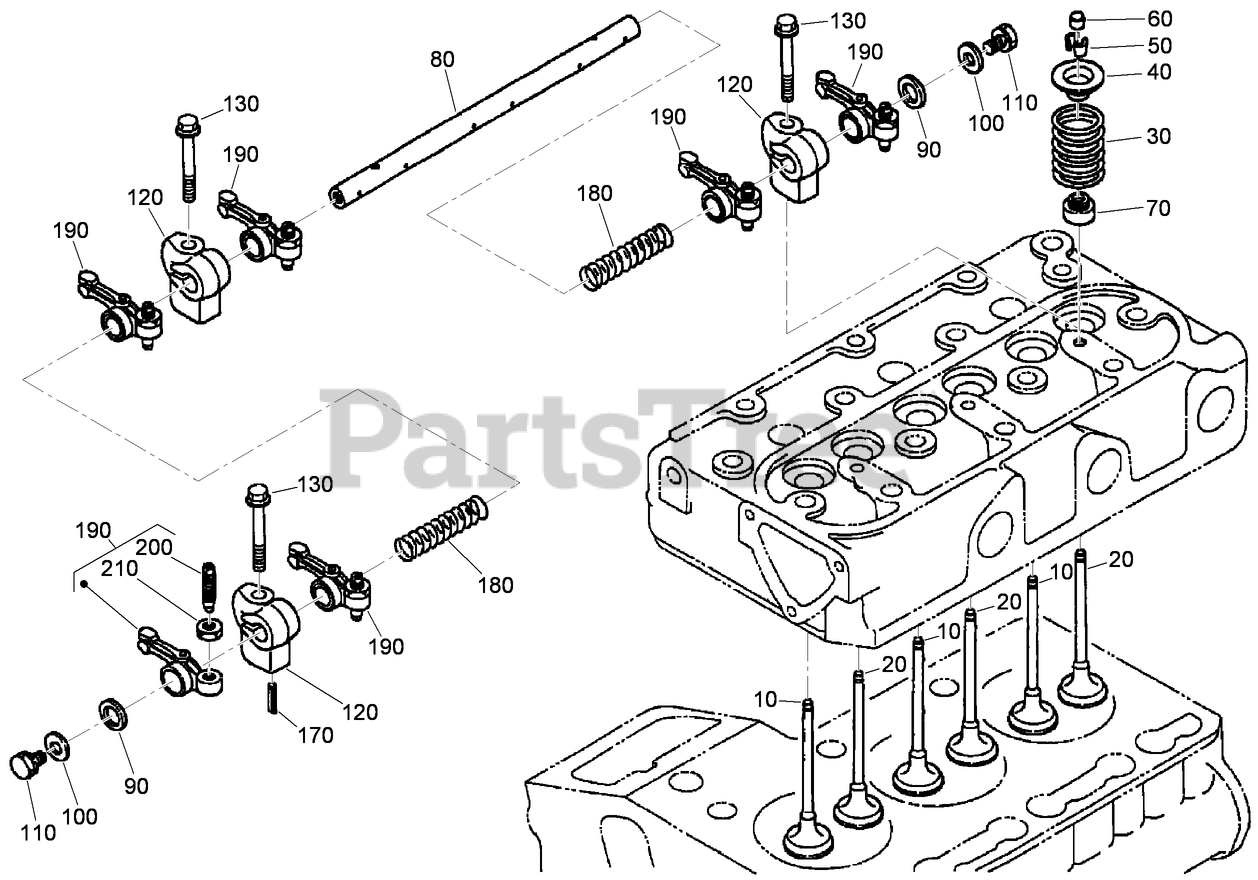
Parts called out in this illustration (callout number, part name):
10	VALVE-INLET
20	VALVE-EXHAUST
30	SPRING-VALVE
40	RETAINER-SPRING, VALVE
50	COLLET-SPRING, VALVE
60	CAP-VALVE
70	SEAL-STEM, VALVE
80	SHAFT-ARM, ROCKER
90	WASHER
100	WASHER-PLAIN
120	BRACKET-ARM, ROCKER
130	BOLT-FLANGE
170	PIN-SPRING
180	SPRING
190	ROCKER ARM ASM
200	SCREW-ADJUSTING
